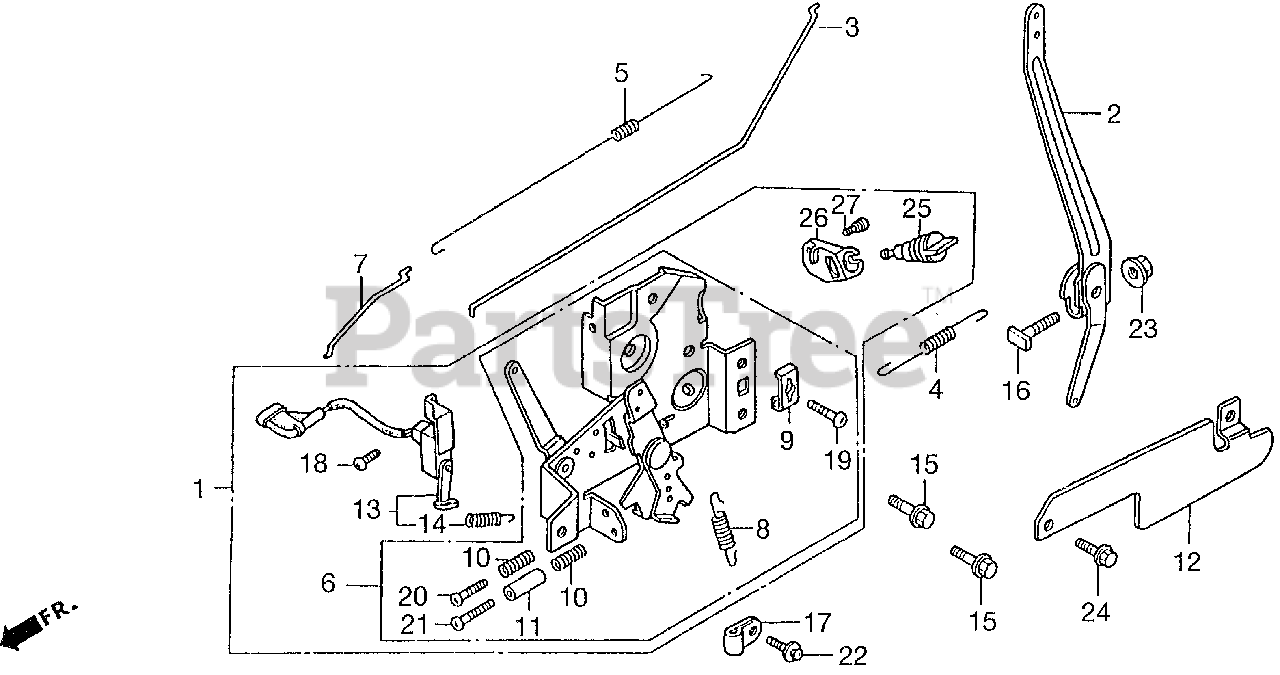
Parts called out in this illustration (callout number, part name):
1	CONTROL ASSY. (BRAKE)
2	ARM, GOVERNOR (C,G)
3	ROD, GOVERNOR
4	SPRING, GOVERNOR
5	SPRING, THROTTLE RETURN
7	ROD, CHOKE
8	SPRING, LEVER
9	HOLDER, CABLE
10	SPRING, CONTROL ADJUSTING
11	COLLAR, STOPPER
13	SWITCH ASSY., ENGINE STOP
14	SPRING, SWITCH CONTROL
15	BOLT, FLANGE (6X14)
16	BOLT, GOVERNOR ARM
18	SCREW, PAN (4X8)
19	SCREW, PAN (5X16)
20	SCREW, PAN (5X20)
21	SCREW, RECESSED (5X25)
23	NUT, FLANGE (6MM)
